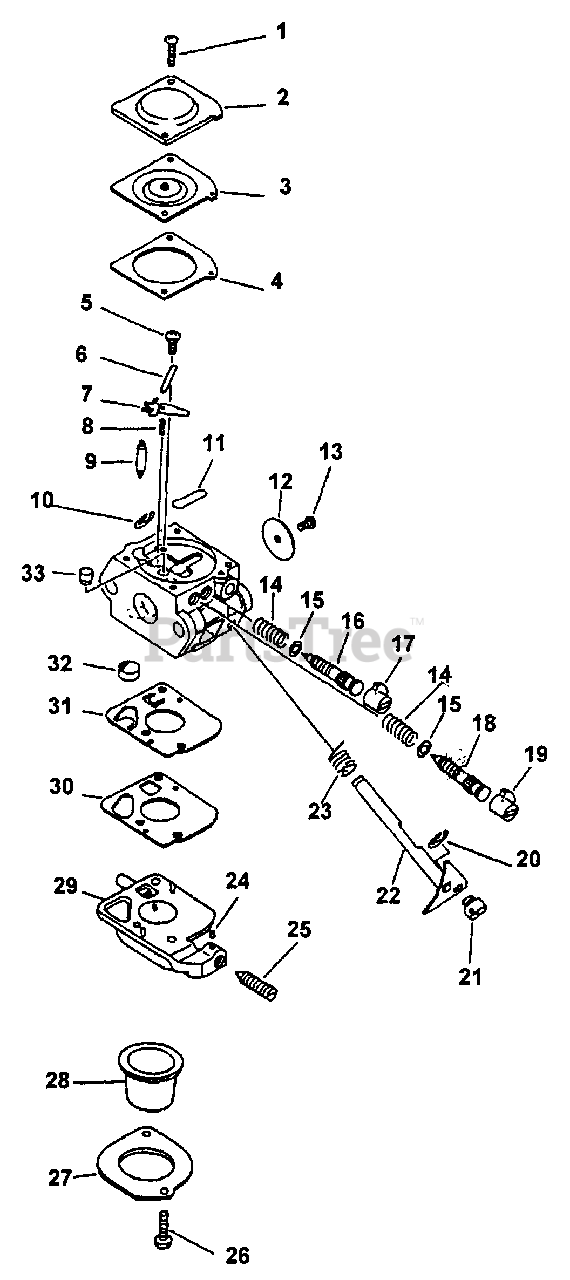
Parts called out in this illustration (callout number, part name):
2	COVER, METERING
3	DIAPHRAGM, METERING
4	GASKET, METERING
5	SCREW, METERING LEVER PIN
6	PIN, METERING LEVER
7	LEVER, METERING
8	SPRING, METERING LEVER
9	VALVE, INLET NEEDLE
10	RING, RETAINING
11	PLUG, WELCH
12	VALVE, THROTTLE
16	NEEDLE - LOW SPEED
17	CAP, LIMITER
18	NEEDLE - HIGH SPEED
19	CAP, LIMITER
20	RING, RETAINING
22	SHAFT, THROTTLE
23	SPRING, RETURN
24	PIECE, FRICTION
25	SCREW, IDLE ADJUST
26	SCREW, RETAINER
27	RETAINER, PURGE BULB
28	BULB, PURGE
29	BASE, PURGE
30	GASKET, PURGE
31	DIAPHRAGM, PURGE
32	STRAINER
33	NOZZLE, CHECK VALVE
